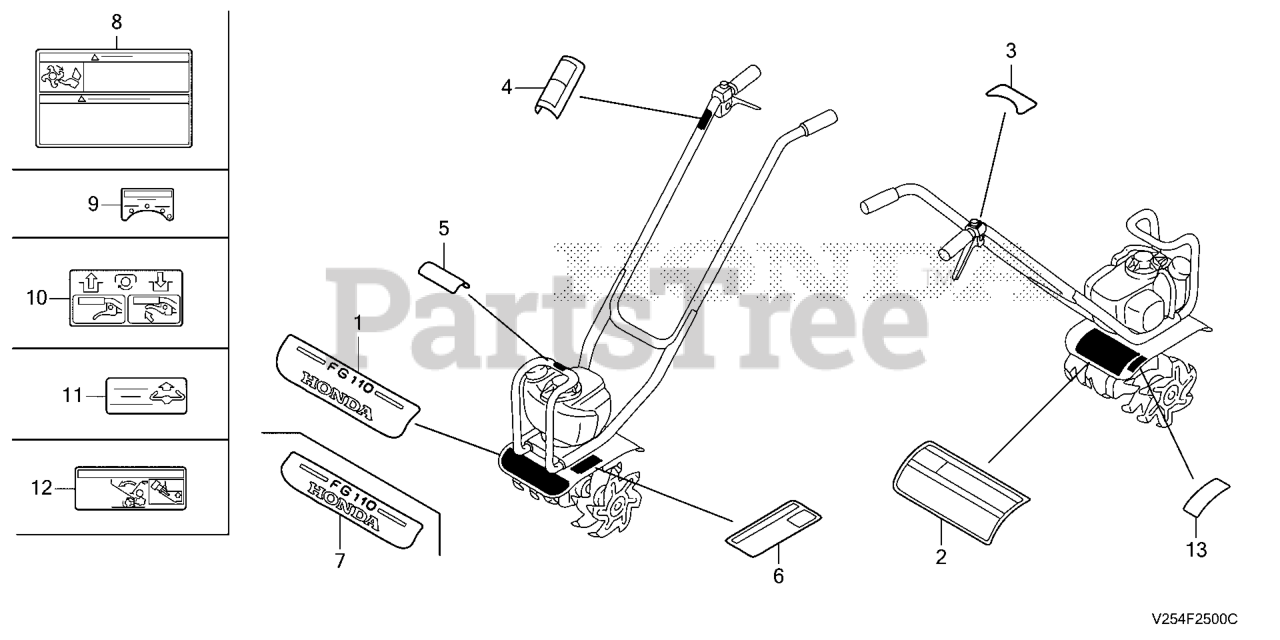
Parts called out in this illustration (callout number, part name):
2	LABEL, TINE DANGER (ENGLISH)
3	MARK, ENGINE SWITCH INDICATION
4	MARK, CLUTCH INDICATION (ENGLISH)
5	MARK, HOLD POSITION (ENGLISH)
6	MARK, OIL LEVEL CHECK (ENGLISH)
7	MARK, STRIPE
13	LABEL, WARNING
